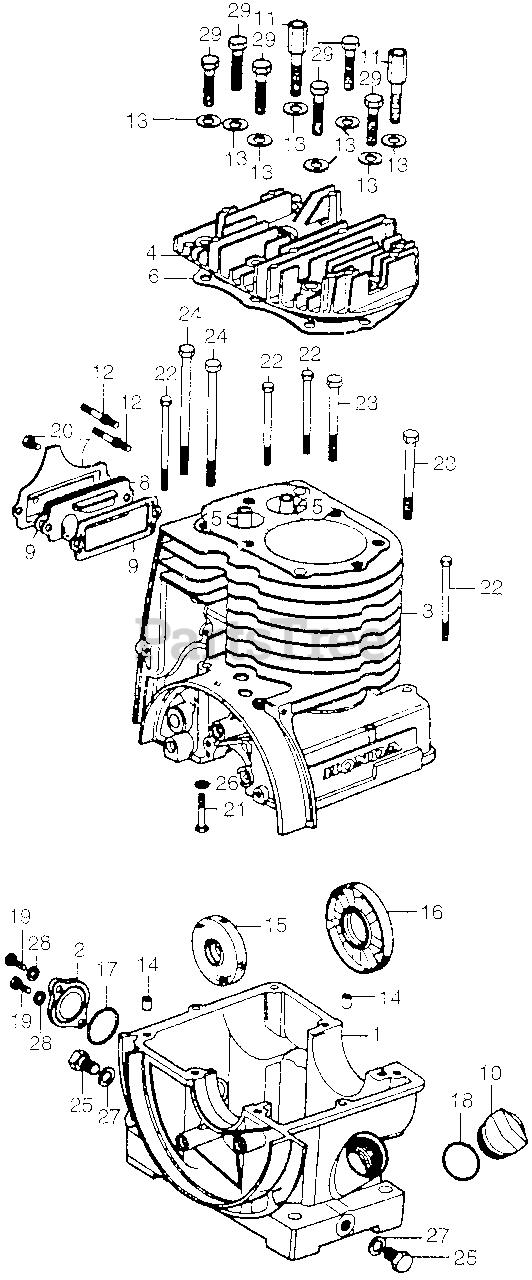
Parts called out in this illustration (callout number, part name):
2	COVER, OIL PAN
4	CYLINDER HEAD
5	GUIDE, VALVE
6	GASKET, CYLINDER HEAD
7	COVER, TAPPET
8	SEPARATOR, OIL
9	GASKET, BREATHER CASE
11	BOLT, CYLINDER HEAD CLAMP
12	BOLT, STUD (8X39) (NOT AVAILABLE)
13	WASHER, HEAD (8MM)
14	PIN, KNOCK (8.5X11) (NOT AVAILABLE)
15	OIL SEAL (PJ20528)
16	OIL SEAL (30X65X10) (NOT AVAILABLE)
17	O-RING (27X2.0)
18	O-RING (26X2.7)
19	BOLT, HEX. (6X12)
20	BOLT, HEX. (6X16)
21	BOLT, HEX. (6X32)
22	BOLT, HEX. (6X70)
23	BOLT, HEX. (8X70)
23	BOLT, HEX. (8X70) (NOT AVAILABLE)
24	BOLT, HEX. (8X100)
25	BOLT, DRAIN PLUG (12MM)
26	WASHER, PLAIN (6MM)
27	WASHER, DRAIN PLUG (12MM)
28	WASHER, SPRING (6MM)
29	BOLT, HEX. (8X36) (SOURCE: VINTAGE PARTS INC.)
